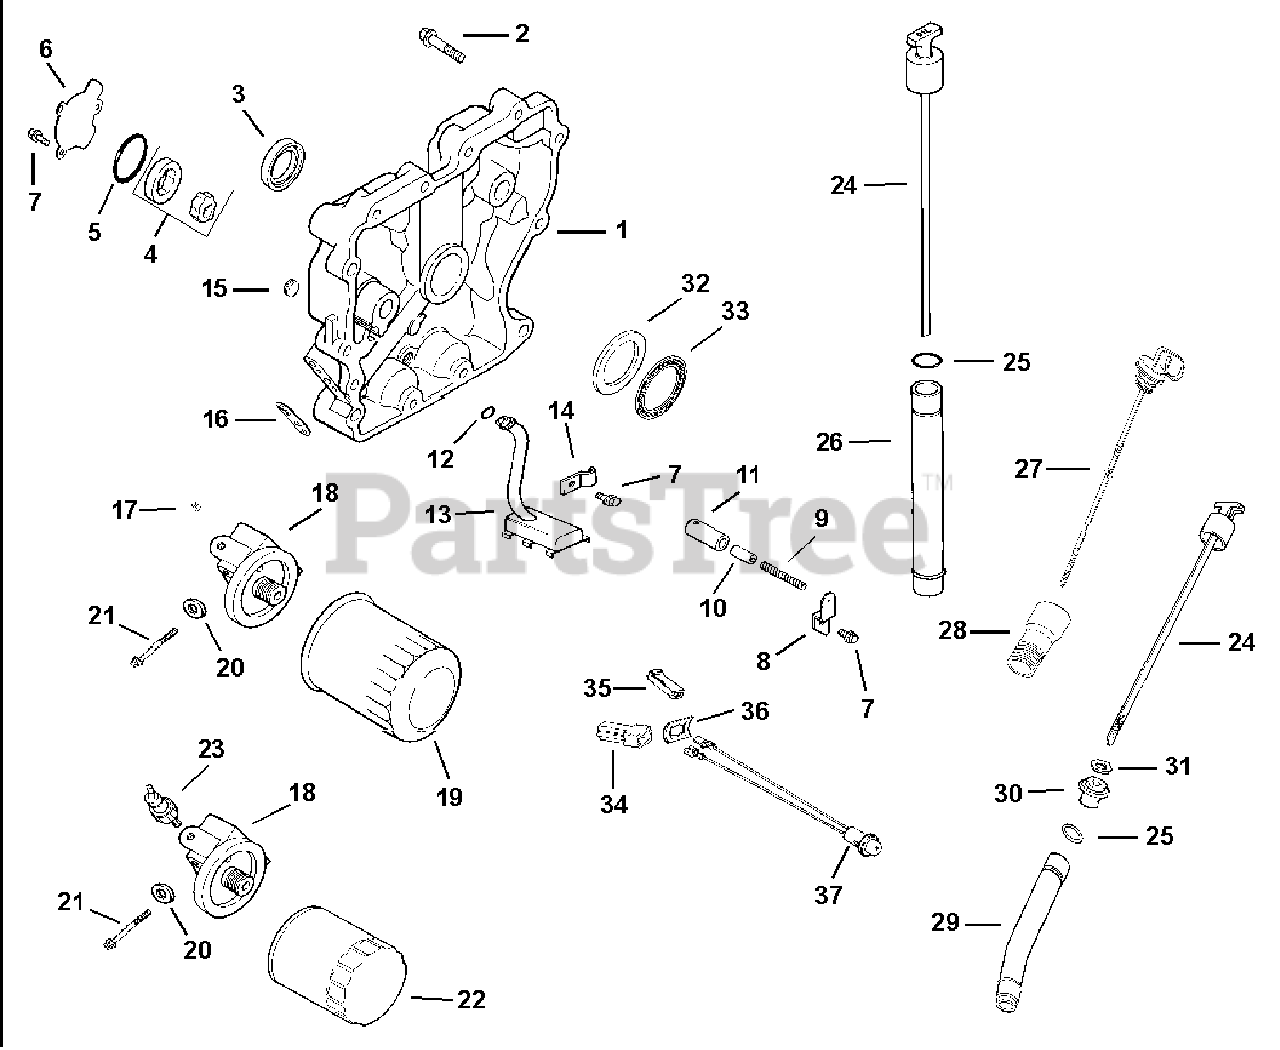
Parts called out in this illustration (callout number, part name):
1	PLATE - USE 12 009 10
2	Screw, hex. flange M8x1.25x45
3	SEAL, OIL
4	PUMP ASSEMBLY, OIL
5	O-RING (1.78" DIA)
7	Screw, hex. flange M5x0.8x16
8	VALVE - USE 25 462 09
9	SPRING - DISCONTINUED
10	VALVE, PISTON RELIEF
11	VALVE - USE 25 462 09
12	O-RING (.5" DIA)
13	KIT - USE 12 755 73
16	GASKET, OIL FILTER ADAPTER
18	ADAPTER - DISCONTINUED
21	Screw, hex. flange M6x1x60
22	OIL FILTER
23	SWITCH - USE 25 099 24
28	TUBE, OIL FILL - DISCONTINUED
